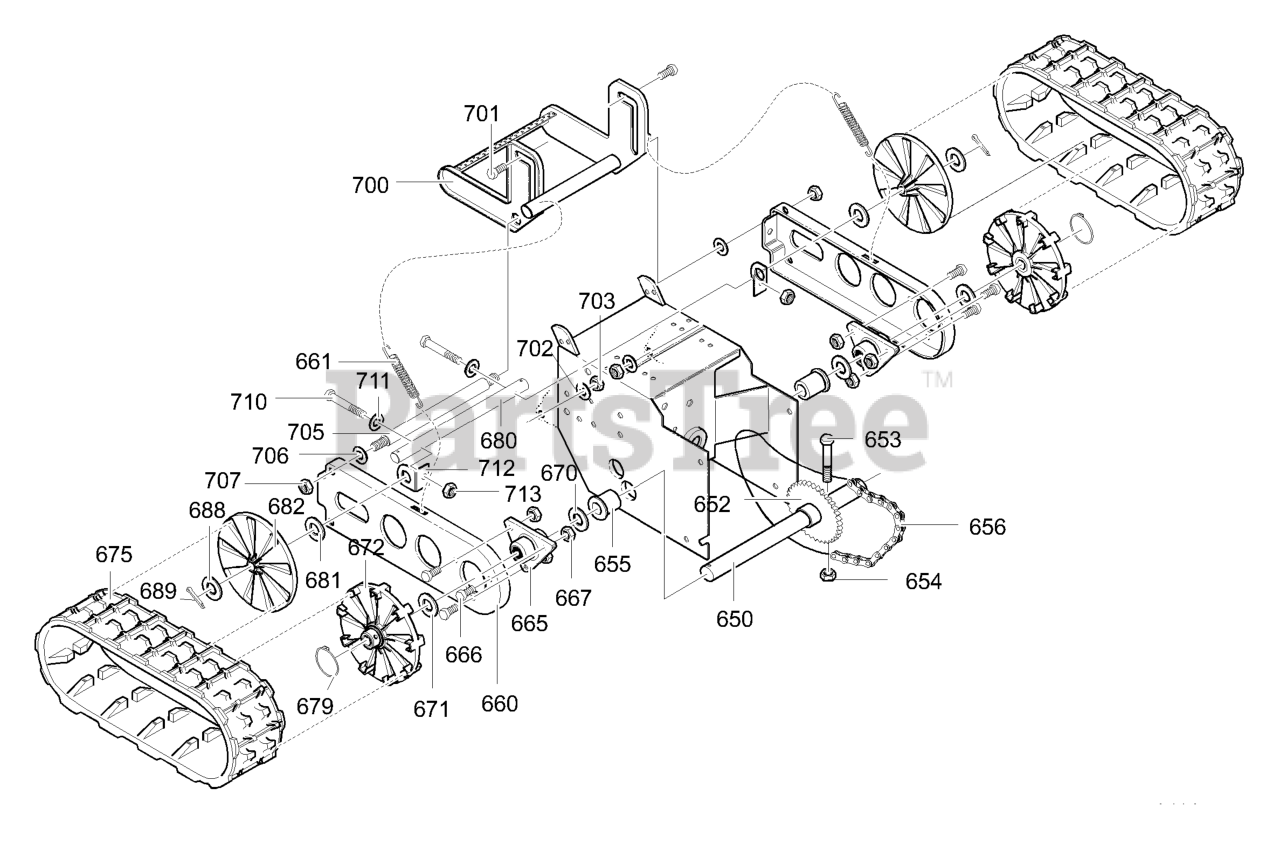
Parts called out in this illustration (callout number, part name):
650	SHAFT, AXLE
652	SPROCKET AND HUB
655	BEARING, FLANGE
656	CHAIN, ROLLER
660	PLATE, TRACK DIRECT
661	SPRING, DRIVE IDLER
665	BEARING, TRACK
670	SPACER
671	WASHER, FLAT
672	SPROCKET, WHEEL
679	PIN, KLIK
680	SHAFT, IDLER
681	WASHER, FLAT
682	WHEEL IDLER
688	WASHER, FLAT
689	PIN, COTTER
700	PEDAL, FOOT
703	NUT
706	WASHER, FLAT
711	WASHER, FLAT
712	BRACKET, TRACK TENSIONER
